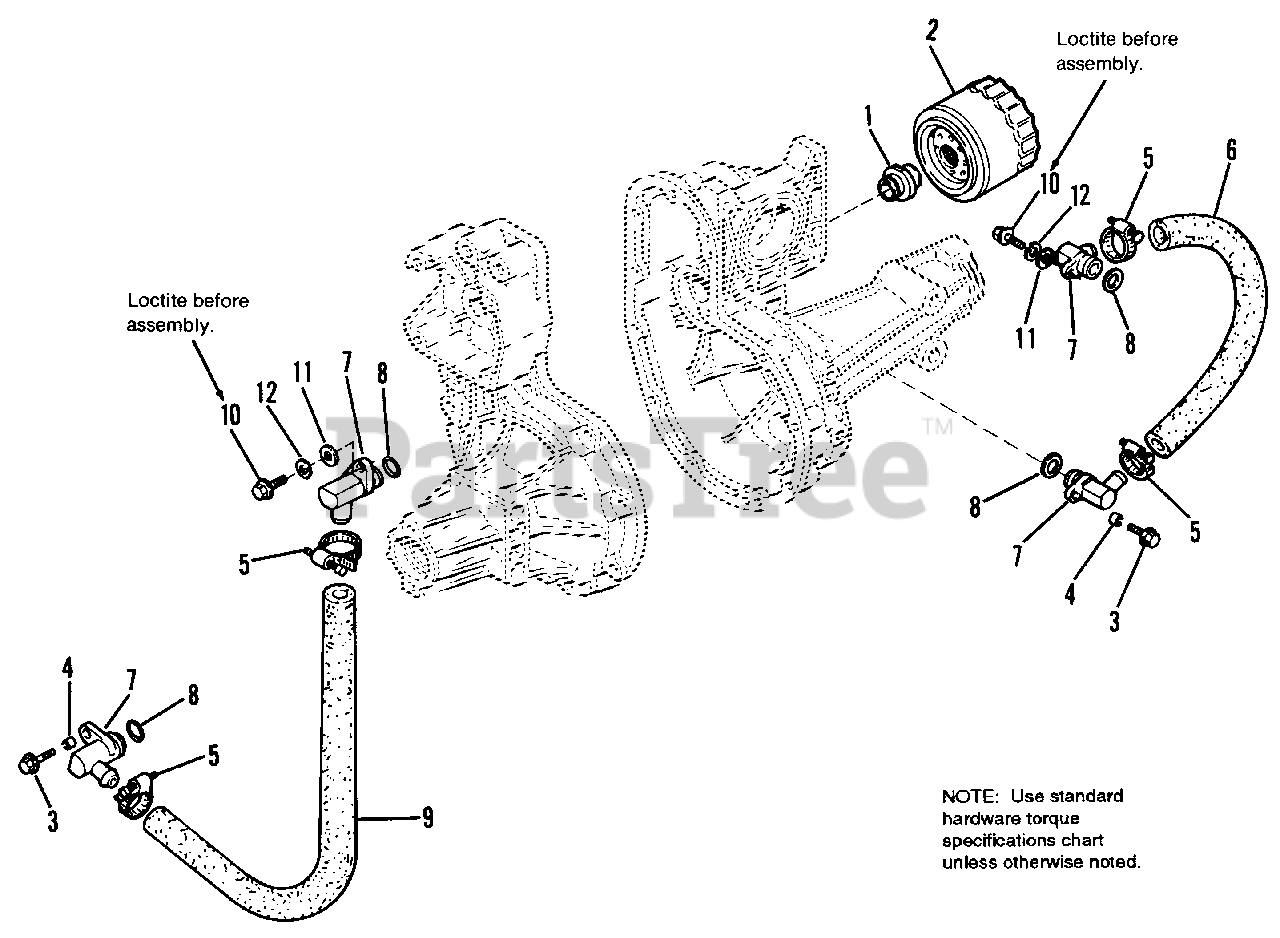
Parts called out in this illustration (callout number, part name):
5	CLAMP, Hose
6	TUBE, Suction
9	TUBE, Drain
11	WASHER, Flat
12	LOCKWASHER
